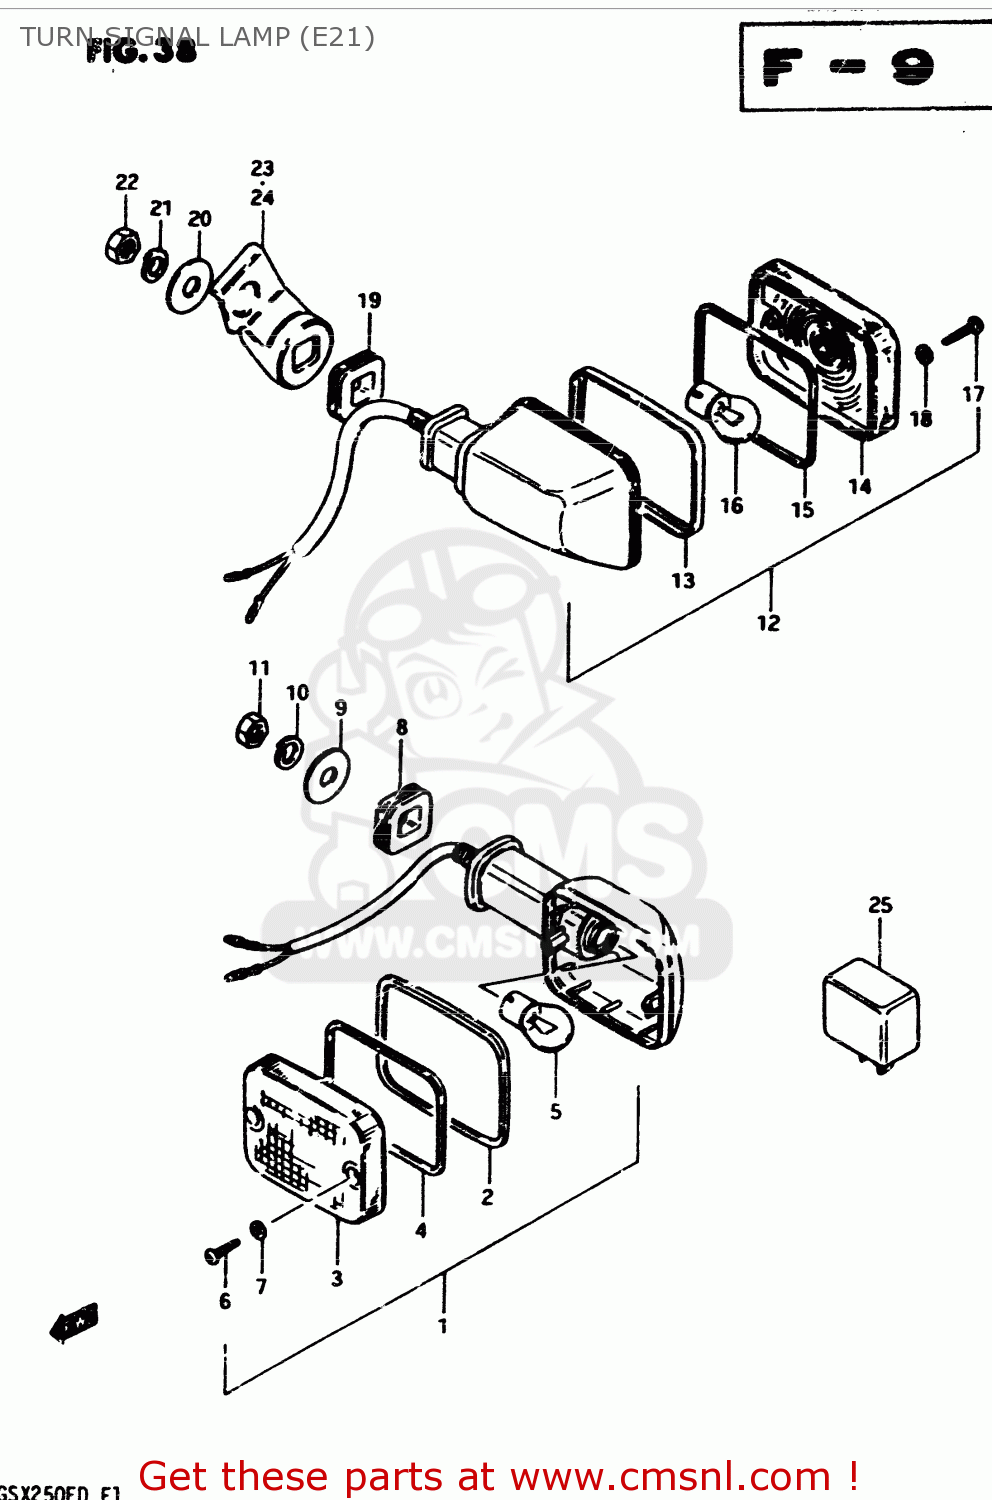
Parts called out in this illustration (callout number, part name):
1	LAMP ASSY,FR T
2	RIM
3	LENS
4	GASKET (NAS)
5	BULB(12V21W)
6	SCREW
7	GASKET (NAS)
8	CUSHION
9	WASHER (10.5X30X2.3)
10	LOCK WASHER
11	NUT
12	LAMP, REAR TURN SIGNAL
13	RIM
14	LENS
15	GASKET (NAS)
16	BULB(12V21W)
17	SCREW
18	GASKET (NAS)
19	CUSHION
20	WASHER (10.5X30X2.3)
21	LOCK WASHER
22	NUT
23	BRACKET,REAR TURN SIGNAL
24	BRACKET,REAR TURN SIGNAL
25	RELAY,TURN SIGNAL
